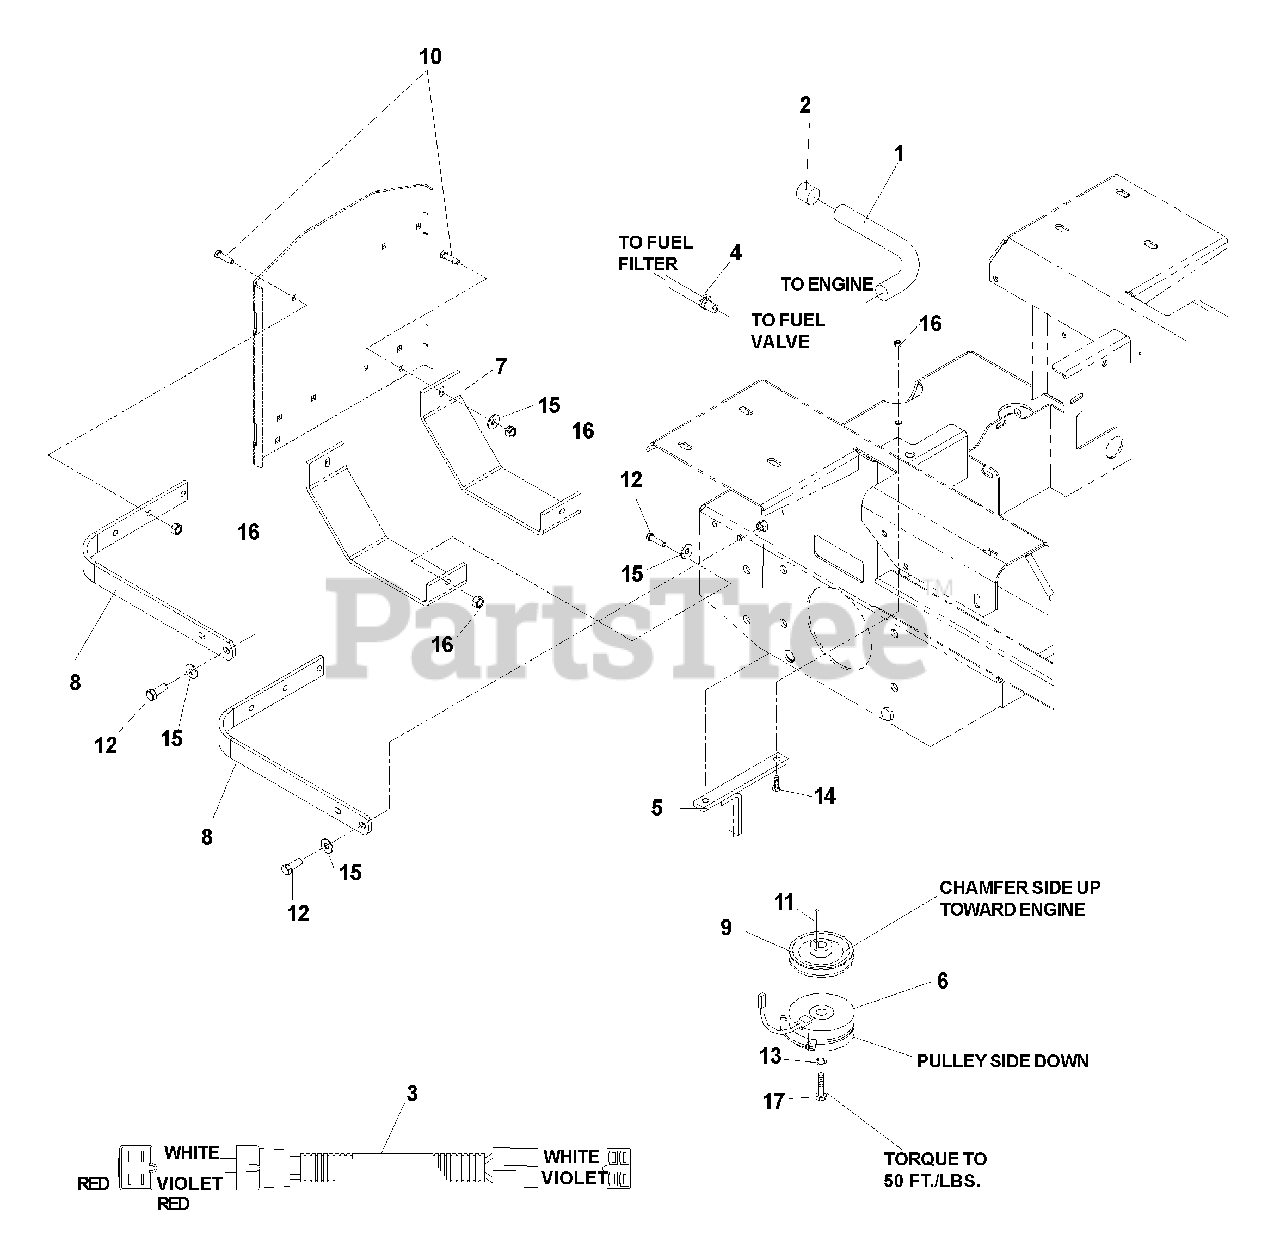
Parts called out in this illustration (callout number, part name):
1	HOSE-DRAIN
3	PIGTAIL, KOHLER
4	FUEL LINE, 13"
5	CLUTCH TIE DOWN
7	SKID PLATE
10	RHSNB, 5/16-18 X 1, GR5
11	KEY, 1/4 SQ X 1 1/4
12	HCS, 5/16-18 X 1, GR5
13	LOCKWASHER, 7/16
14	HCS, 5/16-18 X 1 3/4, GR5
15	WASHER, 5/16
16	NUT, 5/16-18, NYLOC
17	HCS, 7/16-20 X 2 1/2, GR5
